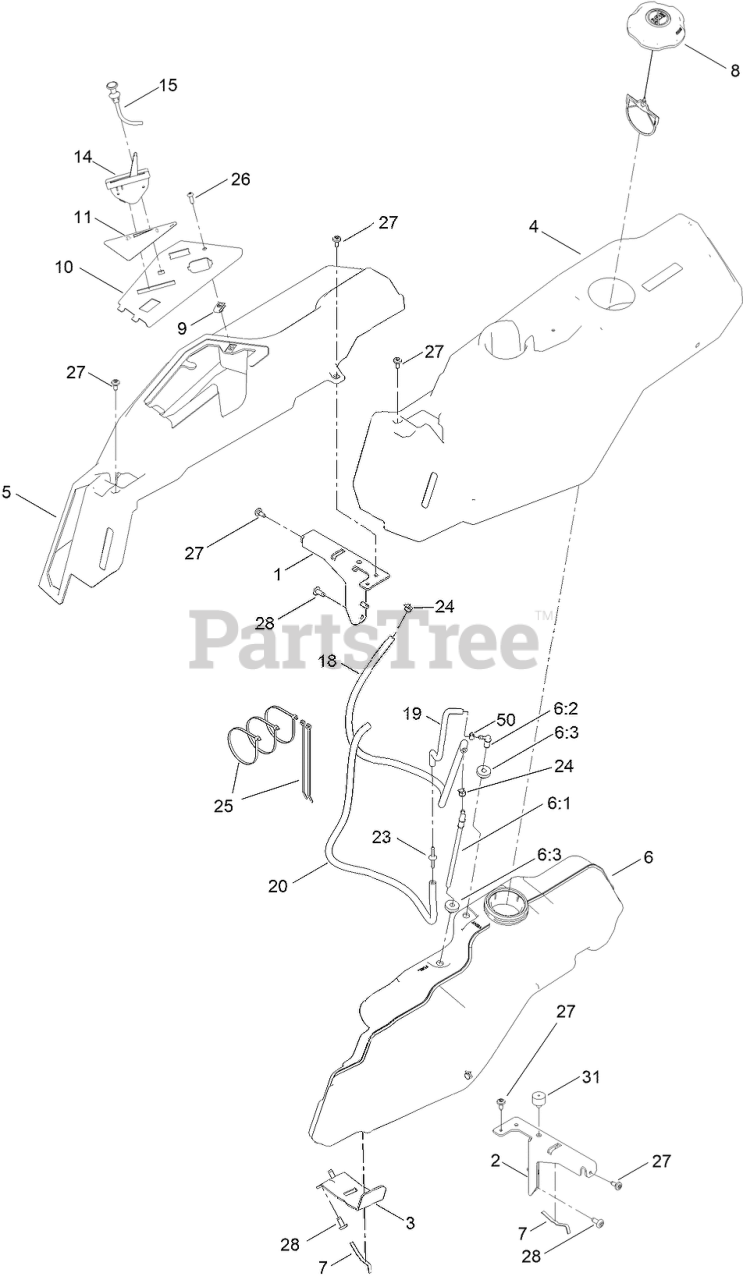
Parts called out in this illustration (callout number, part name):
1	SUPPORT-POD, RH
2	SUPPORT-POD, LH
3	SUPPORT-TANK, FUEL
4	POD-LH
5	POD-RH
6	TANK-FUEL ASM
6:1	CONNECTOR-ELBOW, 90 DEG
6:2	FITTING-ELBOW 90
6:3	BUSHING
7	SPRING
8	CAP-FUEL, RATCHETING
10	PANEL - CONTROL
11	DECAL-PANEL, CONTROL
14	CABLE-THROTTLE
15	CABLE-CHOKE
18	HOSE-FUEL
19	HOSE-FUEL
20	HOSE-FUEL
23	ADAPTER ORIFICE
24	CLAMP-HOSE
25	TIE-CABLE
26	SCREW-PRH
27	SCREW-SHOULDER
31	BUMPER-GROMMET
50	CLAMP-HOSE
